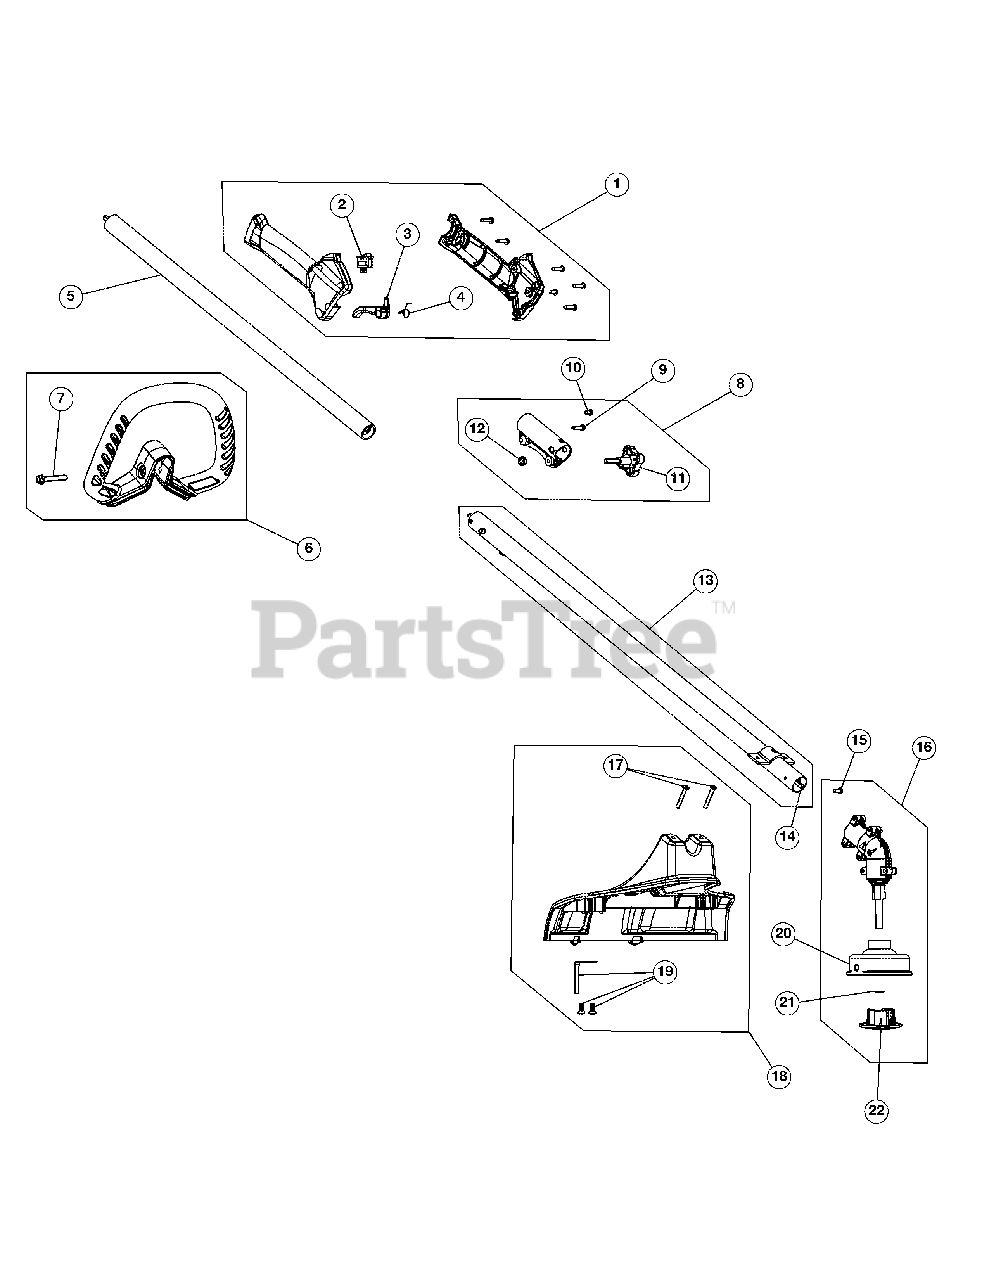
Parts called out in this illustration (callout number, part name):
1	Throttle Housing Assembly (Incl. 2-4)
3	Throttle Trigger
4	Throttle Trigger Spring
5	Upper Shaft Housing Assembly
6	D-Handle (Incl. 7)
7	D-Handle Hardware
8	Split Boom Coupler (Incl. 9-12)
9	Anti-Rotation Screw
11	Adjustment Knob
12	Knob Retainer Nut
13	Lower Shaft Housing Assembly (Incl. 14)
14	Lower Flexible Drive Shaft
15	Anti-Rotation Screw
16	Gear Box Assembly (Incl. 15, 20 & 21)
17	Shield Mounting Screws
18	Shield Assembly (Incl. 17 & 19)
19	Blade Assembly
20	Fixed String Head Assembly (Incl. 21 & 22)
21	Retainer
22	Fixed String Cap
